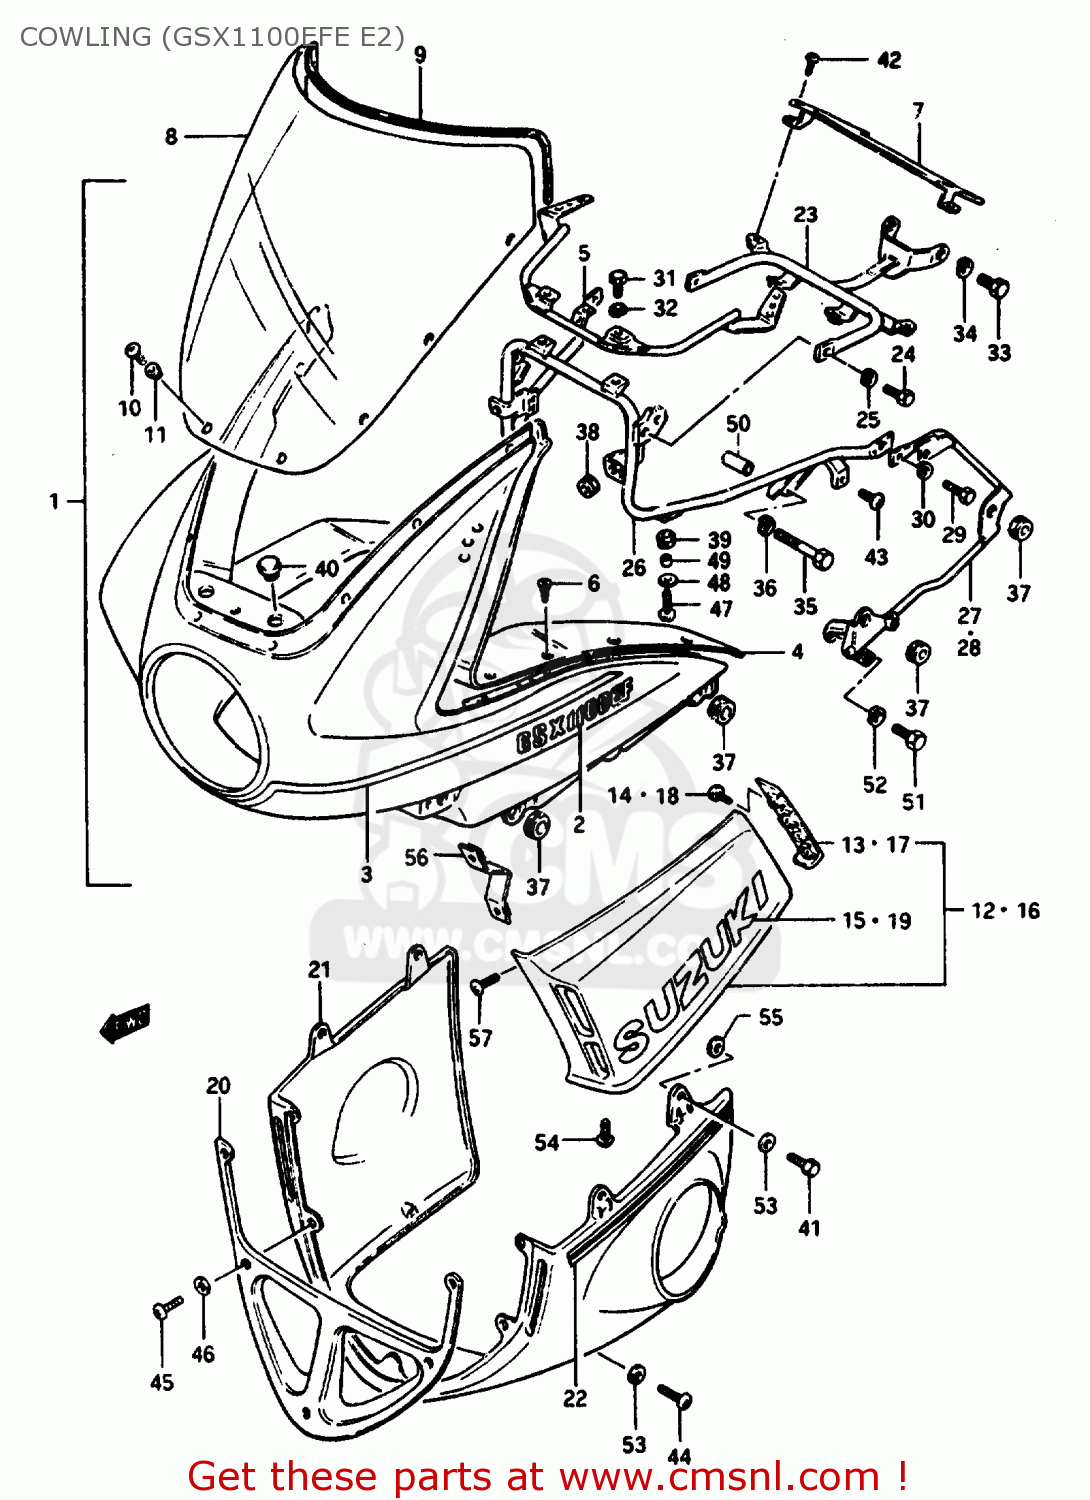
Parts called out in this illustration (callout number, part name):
1	COWLING ASSY (WHITE/BLUE)
2	EMBLEM
3	TAPE SET
4	PANEL,COWLING
5	BRACE,COWLING BODY
6	SCREW, PANEL
7	COVER,METER,REAR
8	WINDOW,COWLING
9	MOLDING COWLING
10	SCREW(5X20)
11	CUSHION
12	COVER, RH (WHITE)
13	PANEL,COWL SIDE COVER RR RH
14	SCREW
15	EMBLEM
16	COVER, LH (WHITE)
17	PANEL,COWLING SIDE COVER
18	SCREW
19	EMBLEM
20	COVER, LOWER (BLUE)
21	COVER (BLUE)
22	TAPE SET
23	BRACE,COWLING,FRONT
24	BOLT
25	LOCK WASHER
26	BRACE,COWL RR
27	BRACE,COWLING SIDE,RIGHT
28	BRACE,COWLING SIDE,LEFT
29	BOLT 6X16
30	LOCK WASHER
31	BOLT
32	LOCK WASHER
33	BOLT
34	LOCK WASHER
35	BOLT
36	LOCK WASHER
37	CUSHION
38	CUSHION
39	CUSHION
40	PLUG(OD:22)
41	SCREW, CENTER
42	SCREW
43	SCREW 6X12
44	SCREW, CENTER
45	SCREW
46	WASHER
47	SCREW, CENTER
48	WASHER(6.5X18X1)
49	SPACER (6.1X9X9)
50	SPACER (8.6X13.8X35)
51	BOLT
52	LOCK WASHER
53	WASHER
54	SCREW
55	WASHER(6X13X2)
56	BRACE,SIDE,FRONT
57	SCREW
